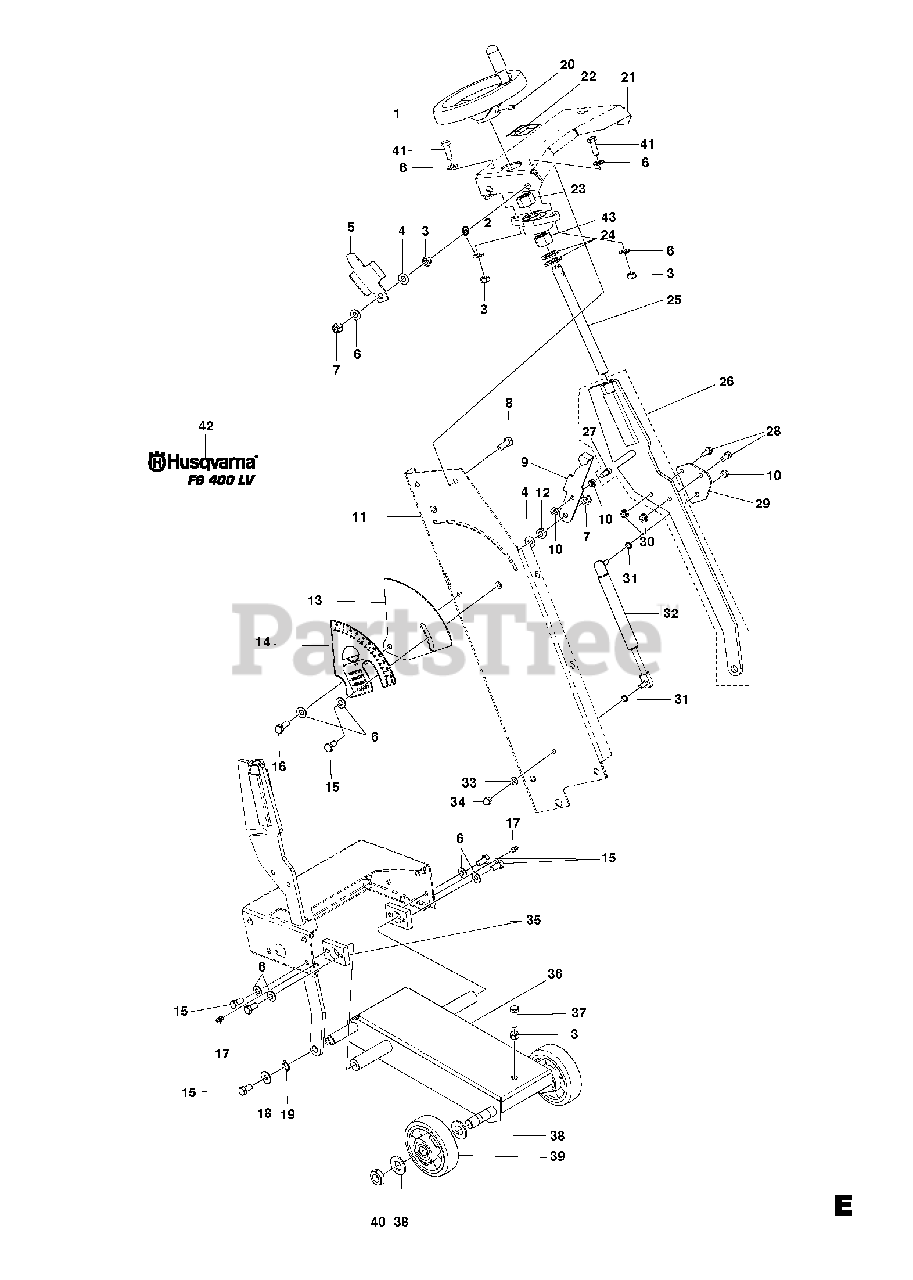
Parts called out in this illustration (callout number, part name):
6	WASHER
7	HEXAGON LOCKING NUT
9	DIAMOND TOOL
10	HEXAGON NUT
30	HEXAGON NUT FLANGE
31	SPRING WASHER
33	WASHER
43	LOCKING PLATE500mm
